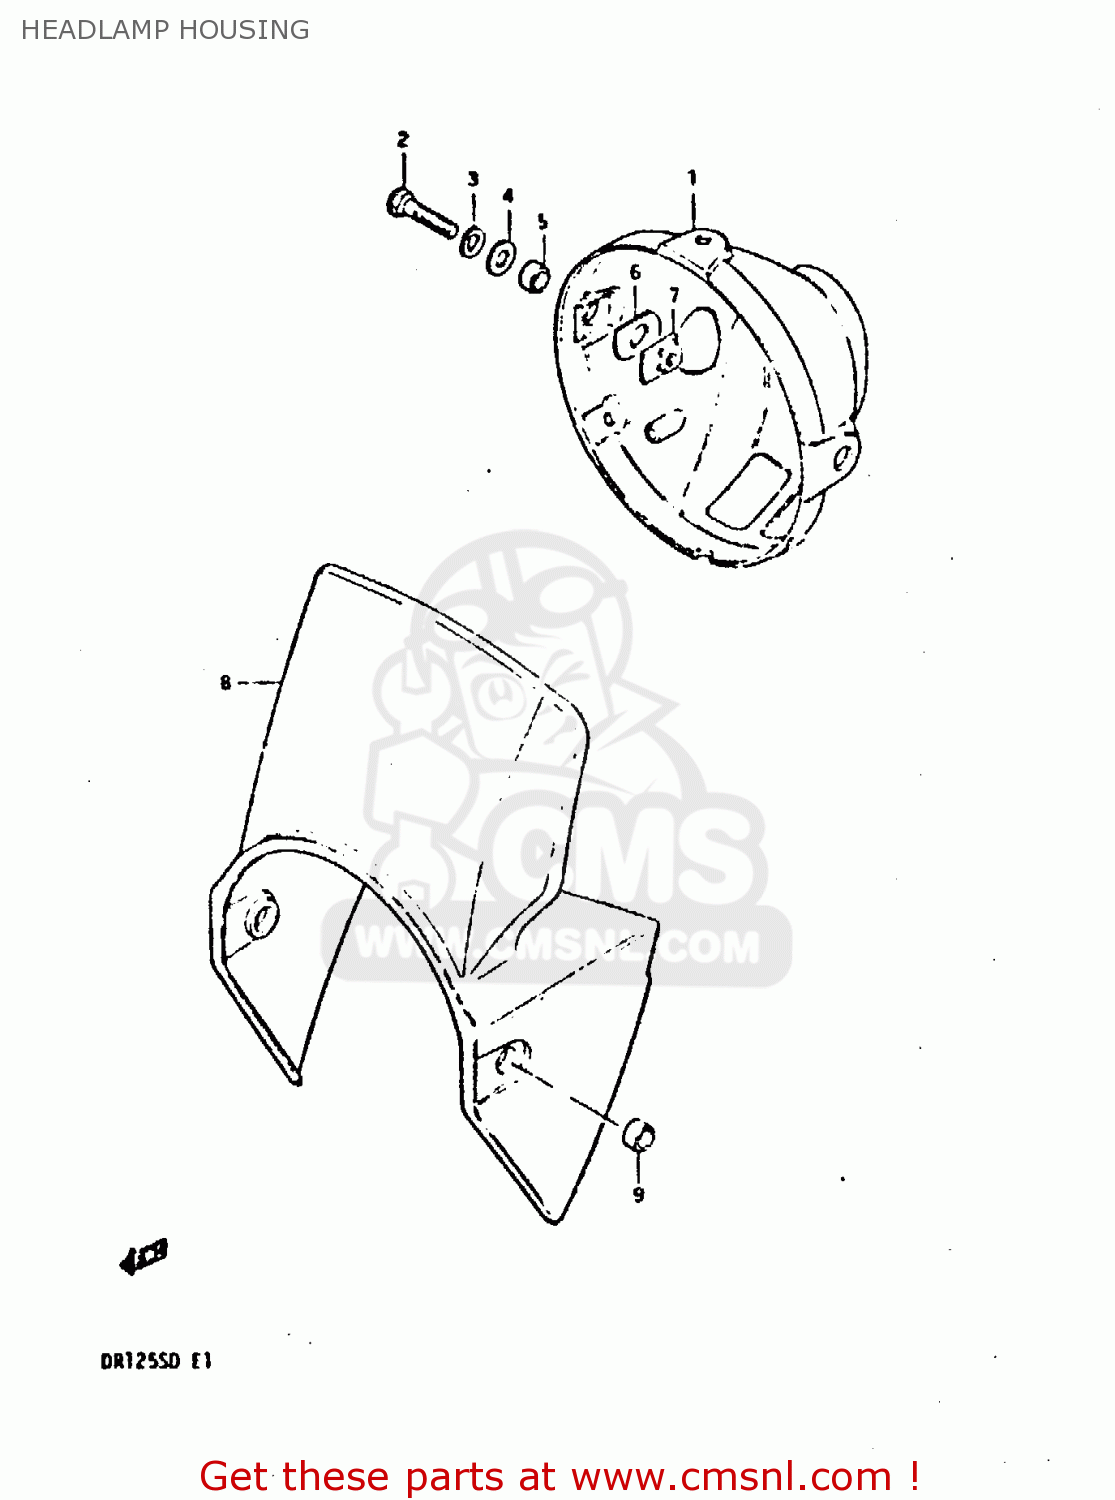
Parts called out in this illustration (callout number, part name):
1	HOUSING,HEAD LAMP
2	BOLT
3	LOCK WASHER
4	WASHER
5	SPACER (8.8X12X7)
6	CUSHION
7	PLATE,HEADLAMP HOUSING
8	COVER, HEADLAMP (BLUE)
9	SPACER (8.8X12X7)
